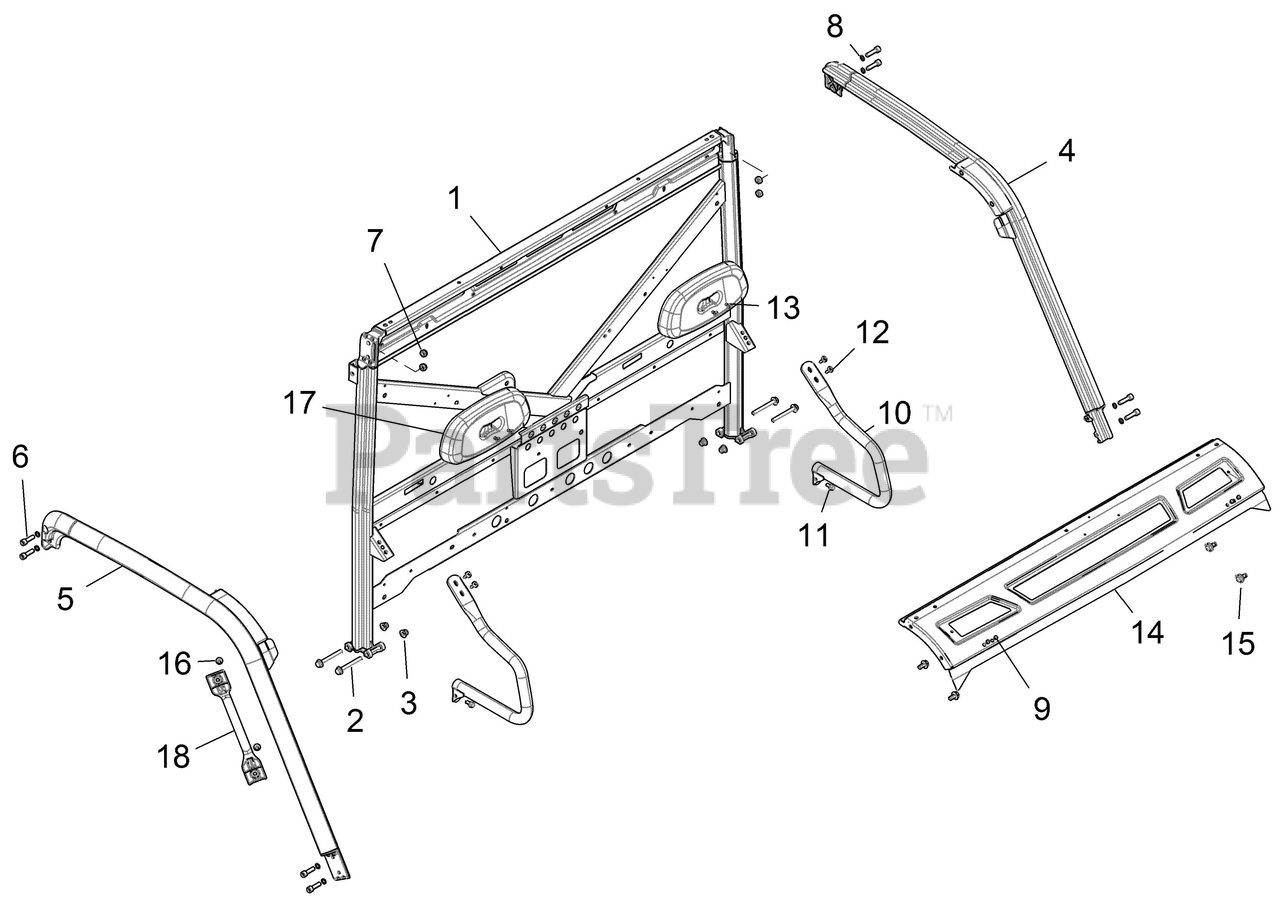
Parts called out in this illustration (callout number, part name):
1	WELD-CAB FRAME,REAR,BLK
2	SCR-HXFL-M10X1.25X80 8.8 ZOD
3	NUT-M10X1.25,FLG,NYLOC-OLIVE D
4	WELD-CAB FRAME,FRT,LH,M.BLK
5	WELD-CAB FRAME,FRT,RH,M.BLK
6	SCR-SH-M10X1.5X35 8.8 ZPB
7	NUT-NYLOC M10X1.5,REF
9	PLUG-FENDER, REAR
10	TUBE-HIP BOLSTER,BLK
11	SCR-HXFL-M8X1.25X20 8.8 ZOD P3
12	SCR-TXTH-M6X1.0X25 RIE
13	RIVET(50)
14	PLATE-WINDSHIELD MNT,UP,M.BLK
15	BOLT-M10X1.5X20,HXFLG,W/PATCH
16	BOLT-M8X1.25X20,HXFLG,TAP/R-OD
17	HEADREST-GRAVELY,GRAY
18	HANDLE-GRAB,ROPS,BLK
